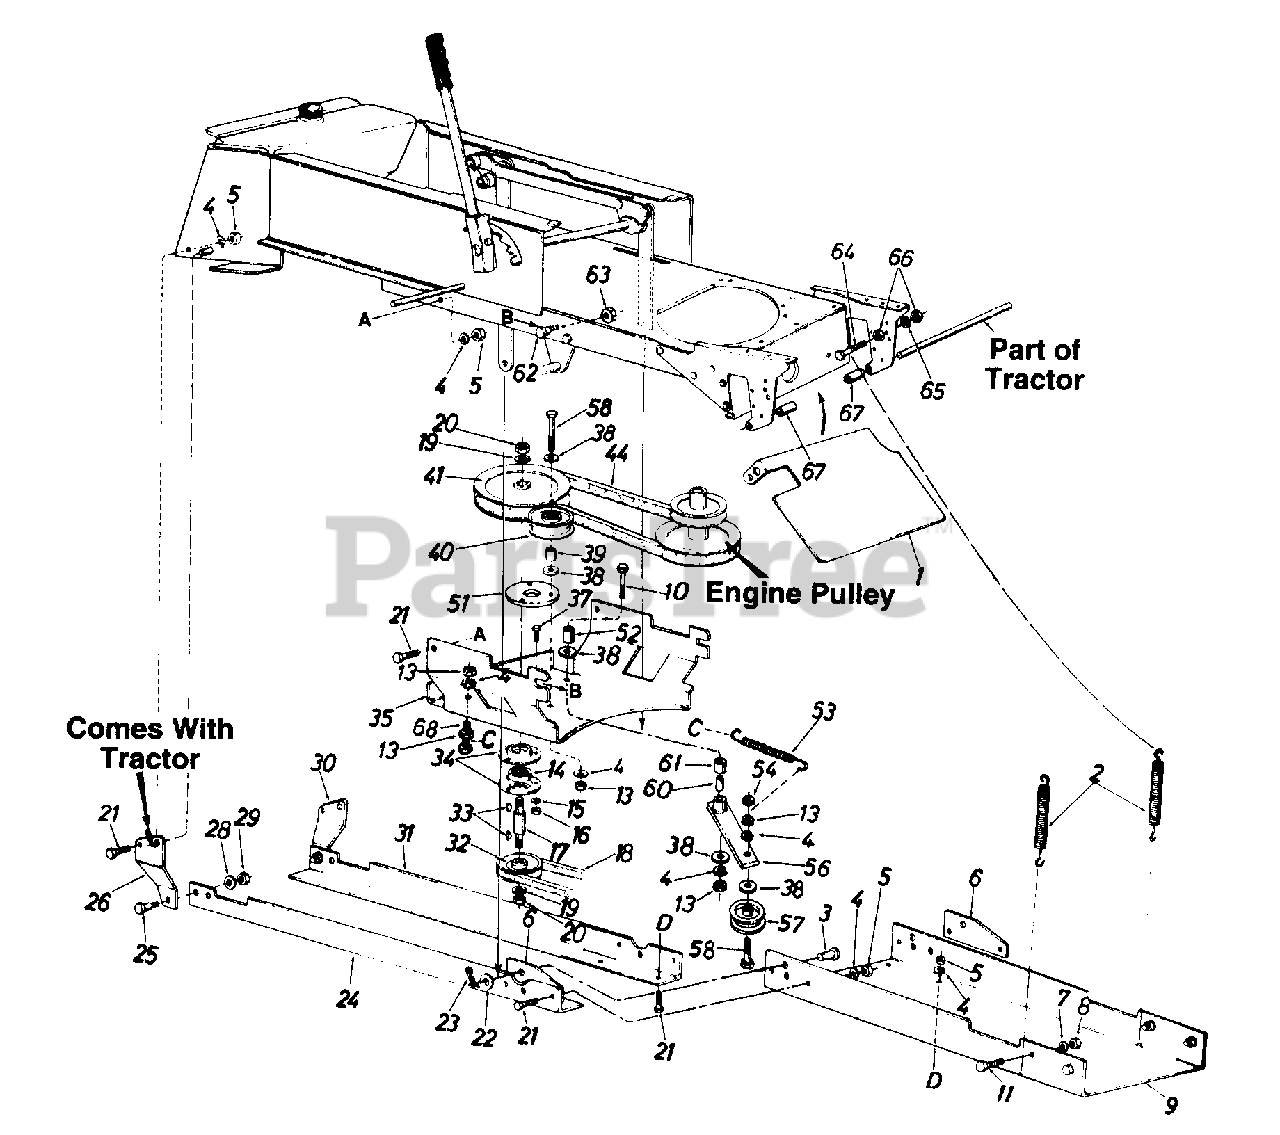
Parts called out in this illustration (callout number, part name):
3	Clevis Pin
4	L-Wash. 3/8" I.D.
5	Hex L-Nut 3/8-24 Thd.
6	Attaching Plate
7	L-Wash. 1/2" I.D.
8	Hex L-Nut 1/2-20 Thd.
11	Hex Bolt 1/2-20 x 1.25" Lg.
13	Hex Jam Nut 3/8-16 Thd.
14	Ball Bearing
15	L-Wash. 5/16" I.D.
16	Hex Nut 5/16-18 Thd.
17	Spindle
18	V-Belt
19	L-Wash. 5/8" I.D.
20	Hex Jam Nut 5/8-11 Thd.
21	Hex Bolt 3/8-24 x 1.00" Lg.
22	Flat Washer
23	Internal Cotter Pin
26	Rear Hanger Brkt.
28	L-Wash. 7/16" I.D.
29	Hex Nut 7/16-14 Thd.
30	Rear Hanger Brkt. - L.H.
31	Rear Support Angle - L.H.
32	Lower Drive Pulley 5/8 x 5.56
33	06 Hi-Pro Key 3/16 x 5/8" Dia.
34	Bearing Housing
35	Supporting Bracket
37	Hex Sems Bolt 5/16-18 x 1"
38	Fl-Wash. .38" I.D. x 1" O.D.
39	Spacer .38" I.D. x .62" O.D.
40	Fl-Idler Pulley
41	Upper Drive Pulley
44	V-Belt
53	Extension Spring 4.75" Lg.
54	Hex L-Nut 3/8-16 Thd.
56	Idle Arm Ass'y.
57	Idler Pulley
58	Hex Bolt 3/8-16 x 2.25" Lg.
60	Spacer .377" I.D. x .83" Lg.
61	Spacer .38" I.D. x .565" Lg.
62	Shoulder Bolt .498" Dia.
63	Hex L-Nut 3/8-16 Thd.
64	Hex Bolt 1/4-28 x 1.50" Lg.
65	L-Wash. 1/4" I.D.
66	Hex Nut 1/4-28 Thd.
67	Spacer .63" I.D. x 1.75" Lg.
68	Hex Bolt 3/8-16 x 2" Lg.
